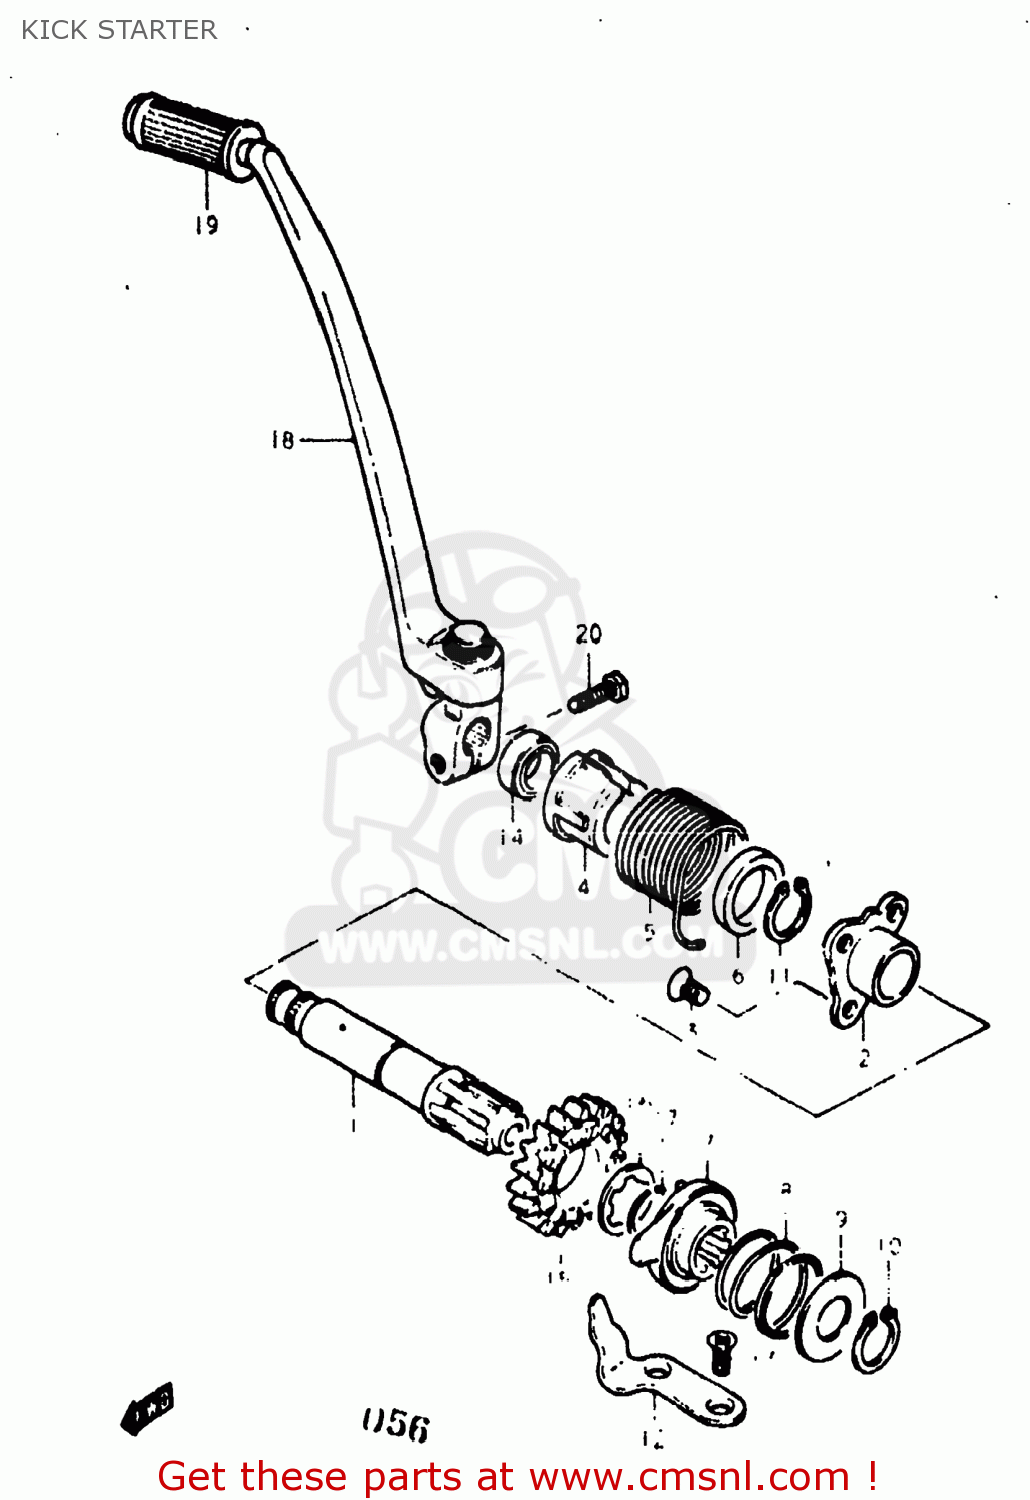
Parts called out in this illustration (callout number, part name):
1	SHAFT,KICK STARTER
2	HOLDER,KICK STARTER SHAFT
3	SCREW
4	GUIDE,KICK SHAFT SPRING
5	SPRING
6	SPACER
7	STARTER,KICK
8	SPRING
9	WASHER
10	CIRCLIP
11	CIRCLIP
12	GUIDE,STARTING SPRING
13	SCREW
14	OIL SEAL
15	GEAR,KICK STARTER DRIVE
16	WASHER,LOCK
17	CIRCLIP
18	LEVER ASSEMBLY,KICK STARTER
19	RUBBER,KICK STARTER PEDAL
20	BOLT
